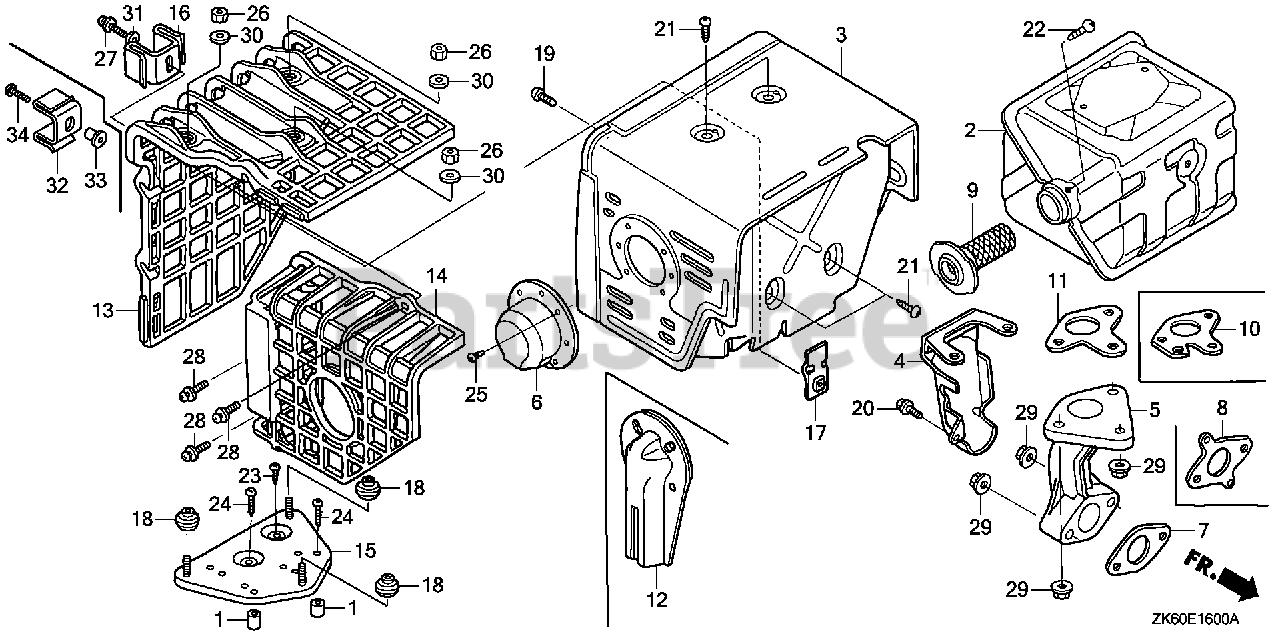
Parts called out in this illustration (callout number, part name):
2	MUFFLER (100DB)
3	PROTECTOR, MUFFLER
4	PROTECTOR, EX. PIPE
6	CAP, MUFFLER
8	GASKET, EX. PIPE
9	ARRESTER, SPARK
10	GASKET, MUFFLER (ARRESTER) (NIPPON LEAKLESS)
11	GASKET, MUFFLER (NIPPON LEAKLESS)
19	SCREW, TAPPING (6X10)
20	BOLT, FLANGE (6X12) (CT200)
21	SCREW, TAPPING (5X8)
22	SCREW, TAPPING (5X8)
25	SCREW, TAPPING (4X6)
29	NUT, FLANGE (8MM)
